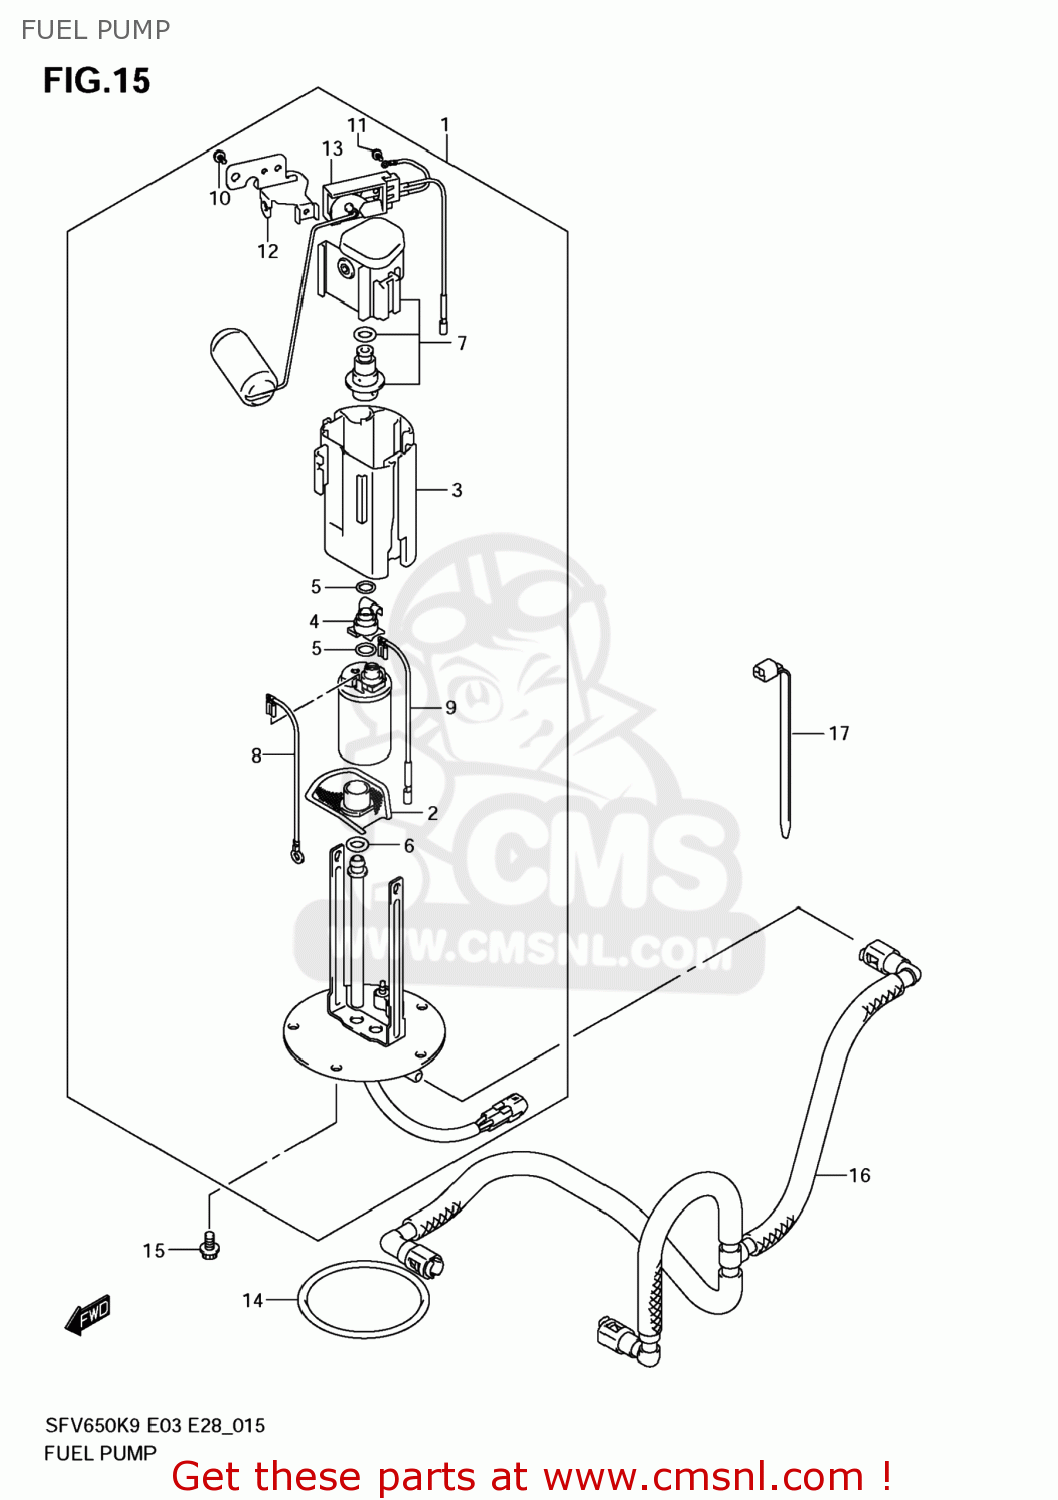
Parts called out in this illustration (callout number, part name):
1	PUMP ASSY,FUEL
2	STRAINER
3	CUP
4	JOINT
5	O RING
6	O RING
7	REGULATOR
8	WIRE,EARTH
9	WIRE,LEAD
10	SCREW
11	SCREW
12	BRACKET,FUEL GAUGE
13	GAUGE ASSY
14	O RING,FUEL PUMP
15	BOLT
16	HOSE,FUEL
17	CLAMP(L:165)
